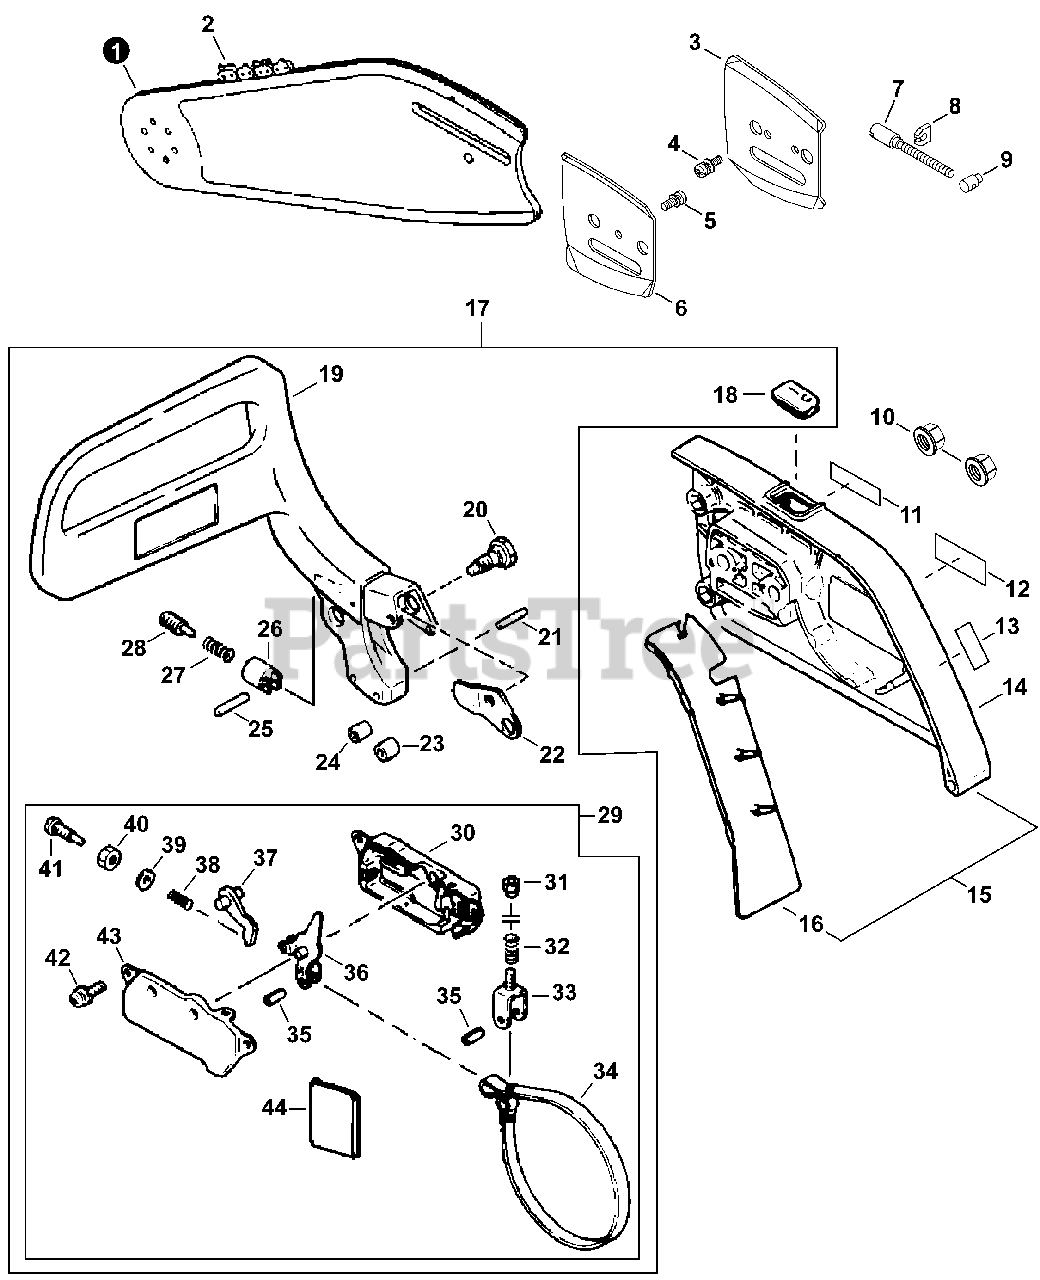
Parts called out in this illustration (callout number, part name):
1	GUIDE BAR - QUICKVENT
2	CHAIN - CARBICHAIN QUICKVENT
3	PLATE, GUIDE - OUTER
4	SCREW 3x6
5	SCREW 4x8
6	PLATE, GUIDE - INNER
7	SCREW, ADJUSTER
9	TENSIONER, CHAIN
10	NUT, FLANGE M8x1.25
11	LABEL - WARNING
12	LABEL - ECHO
13	LABEL - OILER
14	GUARD, SPROCKET - ORANGE
15	GUARD SET, SPROCKET - GRAY
17	BRAKE ASSY, CHAIN - ORANGE
17	BRAKE ASSY, CHAIN - BLACK
19	LEVER, BRAKE - ORANGE
19	LEVER, BRAKE - BLACK
21	PIN 3x18
24	SPACER
25	PIN 2x20
29	BRAKE ASSY, CHAIN
30	COVER, BRAKE
33	ADJUSTER, BRAKE BAND
34	BAND, BRAKE
35	PIN, SPRING 4x10
36	LEVER, BRAKE
37	STOPPER, BRAKE
38	SPRING ,BRAKE
42	BOLT 4x10
44	SEAL, DUST
